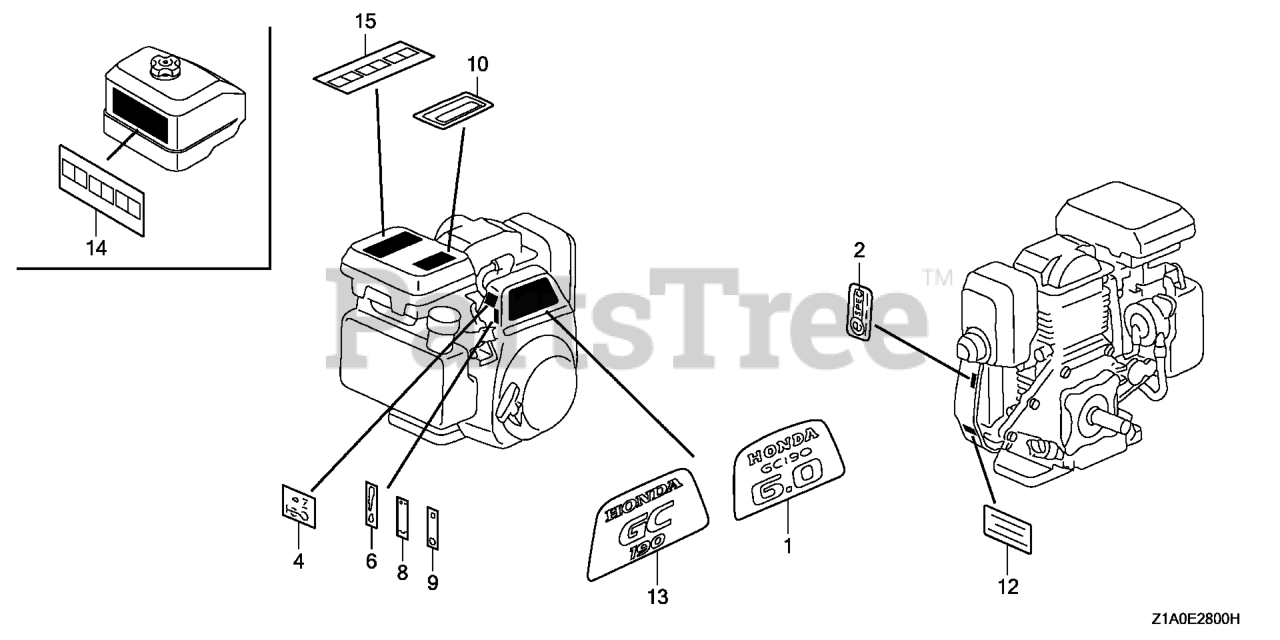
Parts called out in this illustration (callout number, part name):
1	MARK, EMBLEM (GC190)
4	MARK, CHOKE
8	MARK, ENGINE SWITCH INDICATION
10	MARK, OIL ALERT (ENGLISH)
12	LABEL, WARNING (NOT CERTIFIED FOR SALE)
